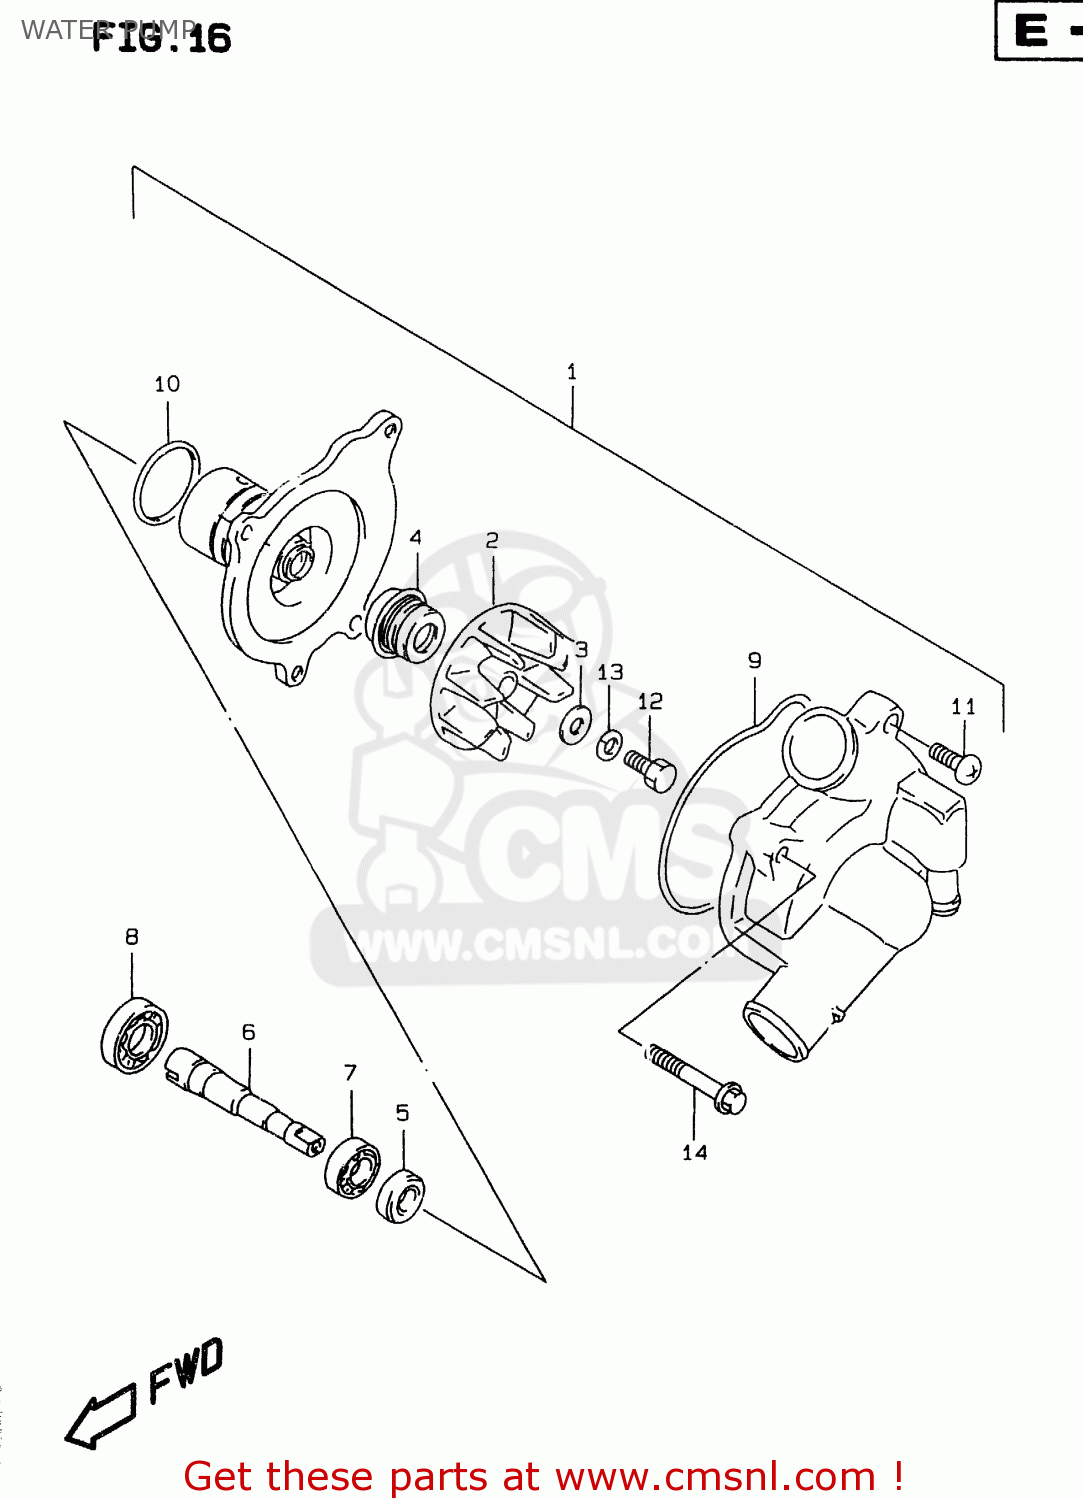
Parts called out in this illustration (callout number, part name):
1	PUMP ASSY,WATER
2	IMPELLER
3	GASKET(6X15X2.2) (NAS)
4	SEAL,MECHANICAL
5	SEAL,OIL(10X21X5)
6	SHAFT,WATER PUMP
7	BEARING(10X26X8)
8	BEARING(12X28X8)
9	O RING
10	O RING,WATER PUMP HOLDER
11	SCREW 6X16
12	BOLT(6X13)
13	WASHER
14	BOLT
